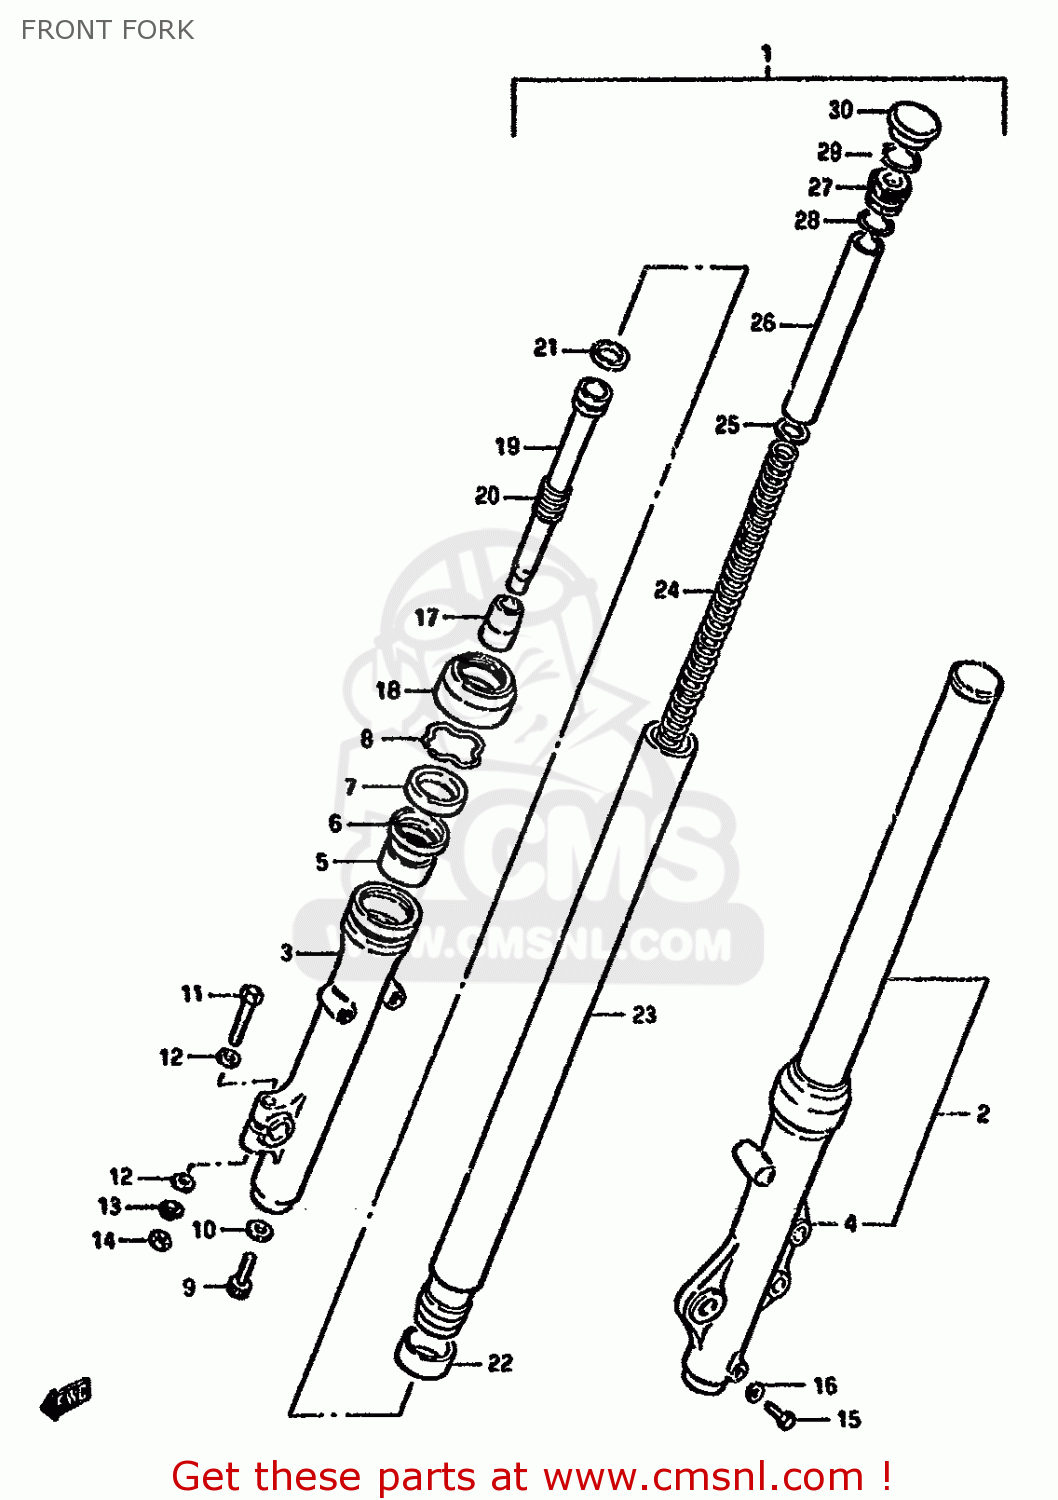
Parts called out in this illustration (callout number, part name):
1	DAMPER ASSEMBLY,RIGHT
2	DAMPER ASSEMBLY,LEFT
3	TUBE,FORK,OUTER,RIGHT
4	TUBE,FORK,LEFT,OUTER
5	BUSH,GUIDE
6	SPACER,OIL SEAL
7	SEAL,OIL
8	CIRCLIP,FORK OIL SEAL
9	BOLT(8X27)
10	GASKET (NAS)
11	BOLT 8X50
12	WASHER
13	LOCK WASHER
14	NUT
15	BOLT
16	GASKET,DRAIN,PLUG (NAS)
17	PIECE,OIL LOCK
18	DUST SEAL
19	CYLINDER
20	SPRING,REBOUND
21	RING,PISTON
22	BUSH
23	TUBE,INNER
24	SPRING
25	SEAT,SPRING
26	SPACER,FRONT FORK SPRING
27	SEAT,SPRING
28	O RING
29	RING,STOPPER
30	CAP
